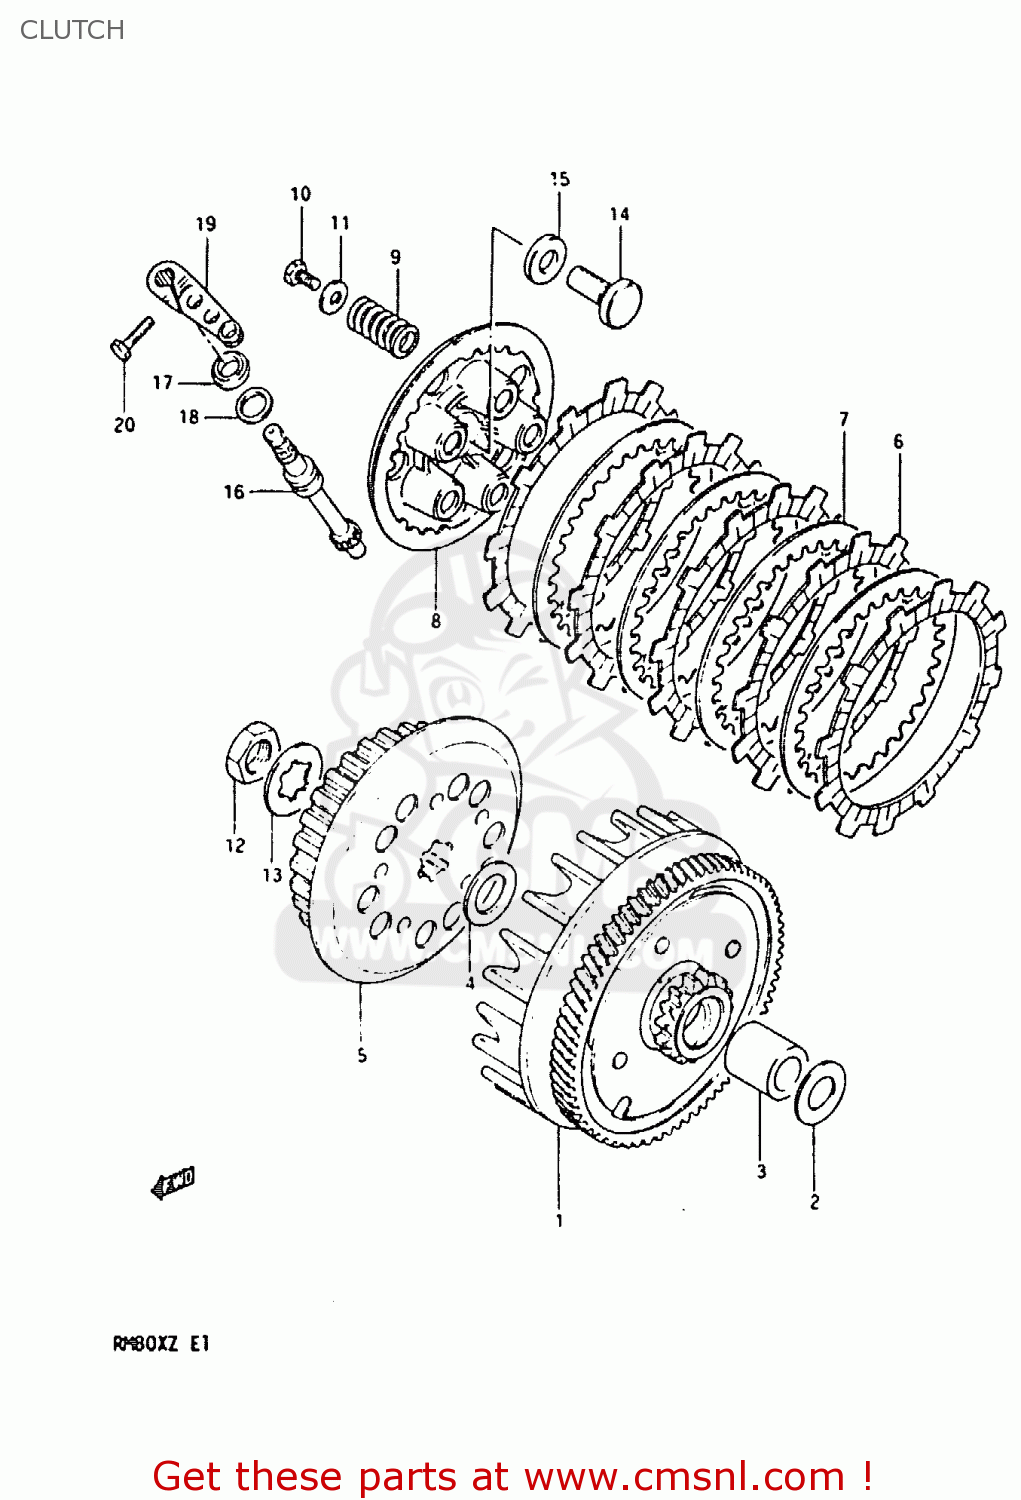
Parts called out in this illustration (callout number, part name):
1	GEAR ASSEMBLY,PRIMARY DRIVE
2	WASHER,THRUST
3	SPACER(17X22X28.5)
4	WASHER
5	HUB,CLUTCH SLEEVE
6	PLATE,CLUTCH DRIVE
7	PLATE,CLUTCH DRIVEN
8	DISC,CLUTCH PRESSURE
9	SPRING
10	BOLT(5X16)
11	WASHER (5.5X16X1.2)
12	NUT
13	WASHER,LOCK
14	RACK,CLUTCH RELEASE
15	BEARING(10X22X2.8)
16	PINION,CLUTCH RELEASE
17	OIL SEAL
18	WASHER (12X17X1)
19	ARM,CLUTCH RELEASE
20	BOLT, UPPER
